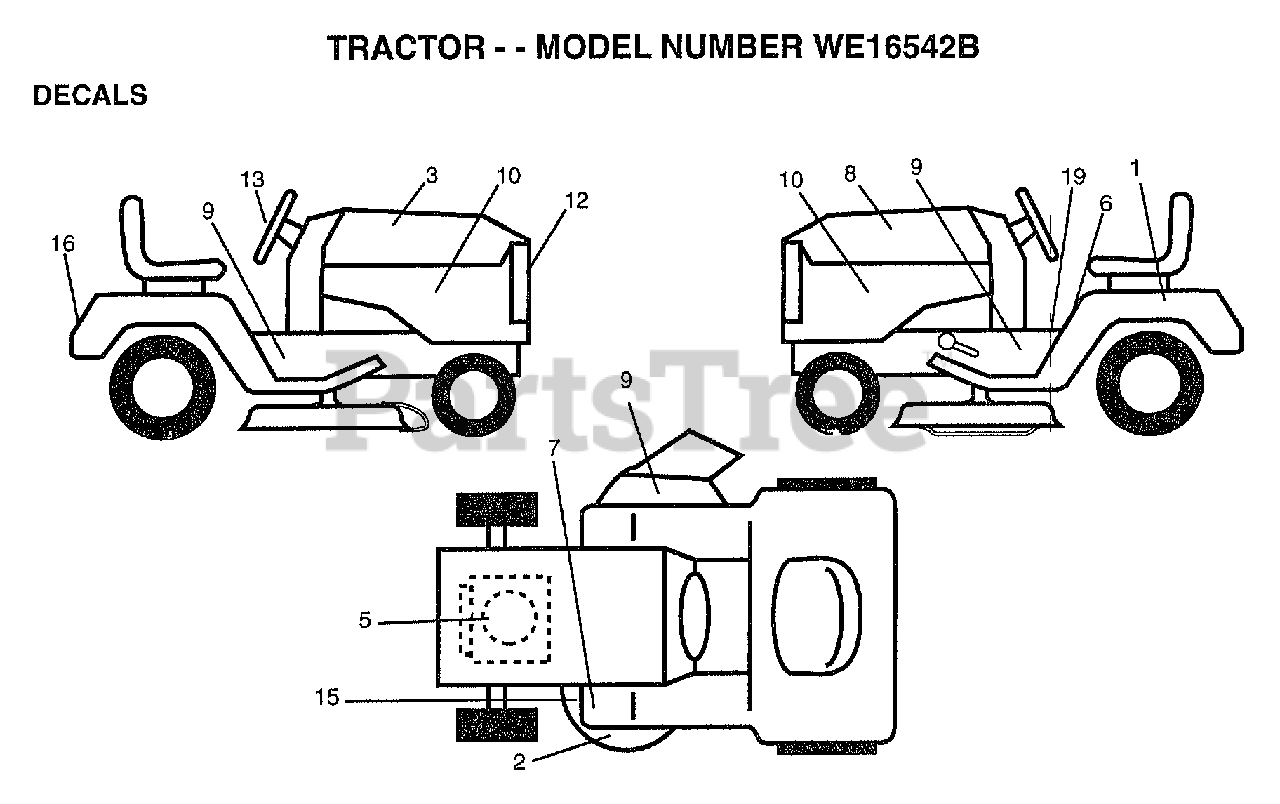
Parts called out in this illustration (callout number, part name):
1	DECAL.BATRY.3-3908
2	DECAL, DECK GRASSEATER
3	DECAL.HOOD.RH.
5	DECAL.ENGINE
6	DECAL.CAUT.ENG/FR
7	DECAL.CLUTCH/BRK
8	DECAL.HOOD.LH
9	"DECAL, WARNING"
10	DECAL PNL SIDE
12	DECAL, GRILLE LENS
13	DECAL, INS STRG WH
15	"DECAL-SCHEM,BELT"
16	DECAL.FENDER.LOGO
19	"DECAL.OPER,SDL"
